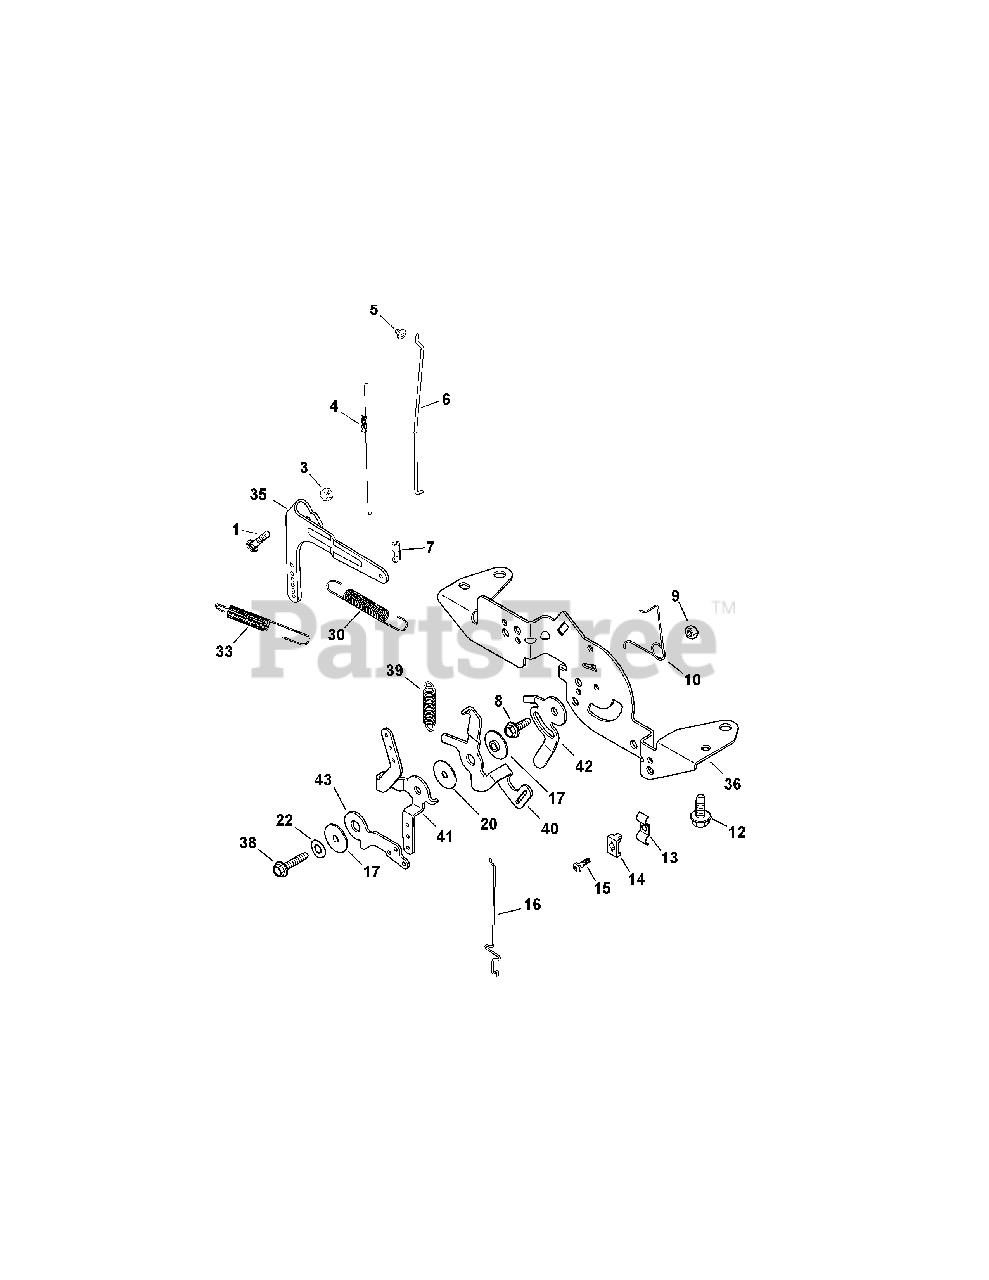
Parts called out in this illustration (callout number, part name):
1	Rd. Hd. Sq. Neck Bolt, M6 x 1.0 x 25
3	Flg. Nut, M6 x 1.0
4	Linkage Spring
5	Linkage Retaining Bushing
6	Throttle Linkage
7	Throttle Linkage Bushing
8	Flg. Thd. Frm. Screw, M5 X 0.8 X 16
9	Nut, M5 x .8, Lock
10	Choke Return Spring
12	Flg. Thd. Frm. Screw, M6 x 1.0 x 16
13	Dual Conduit Clamp
14	Cable Clamp
15	Lbd. Thd. Frm. Screw, M5 x 0.8 x 16
16	Choke Linkage
17	Control Assembly Spacer
20	Flat Washer, 5.5mm
22	Spring Washer, 1/4"
30	Governor Spring
33	Governor Spring
35	Governor Lever
36	Control Bracket
38	Thd. Frm. Screw, M5 x 0.8 x 25
39	Speed Control Spring
40	Governor Spring Lever
41	Speed Control Lever
42	Speed Setting Lever
